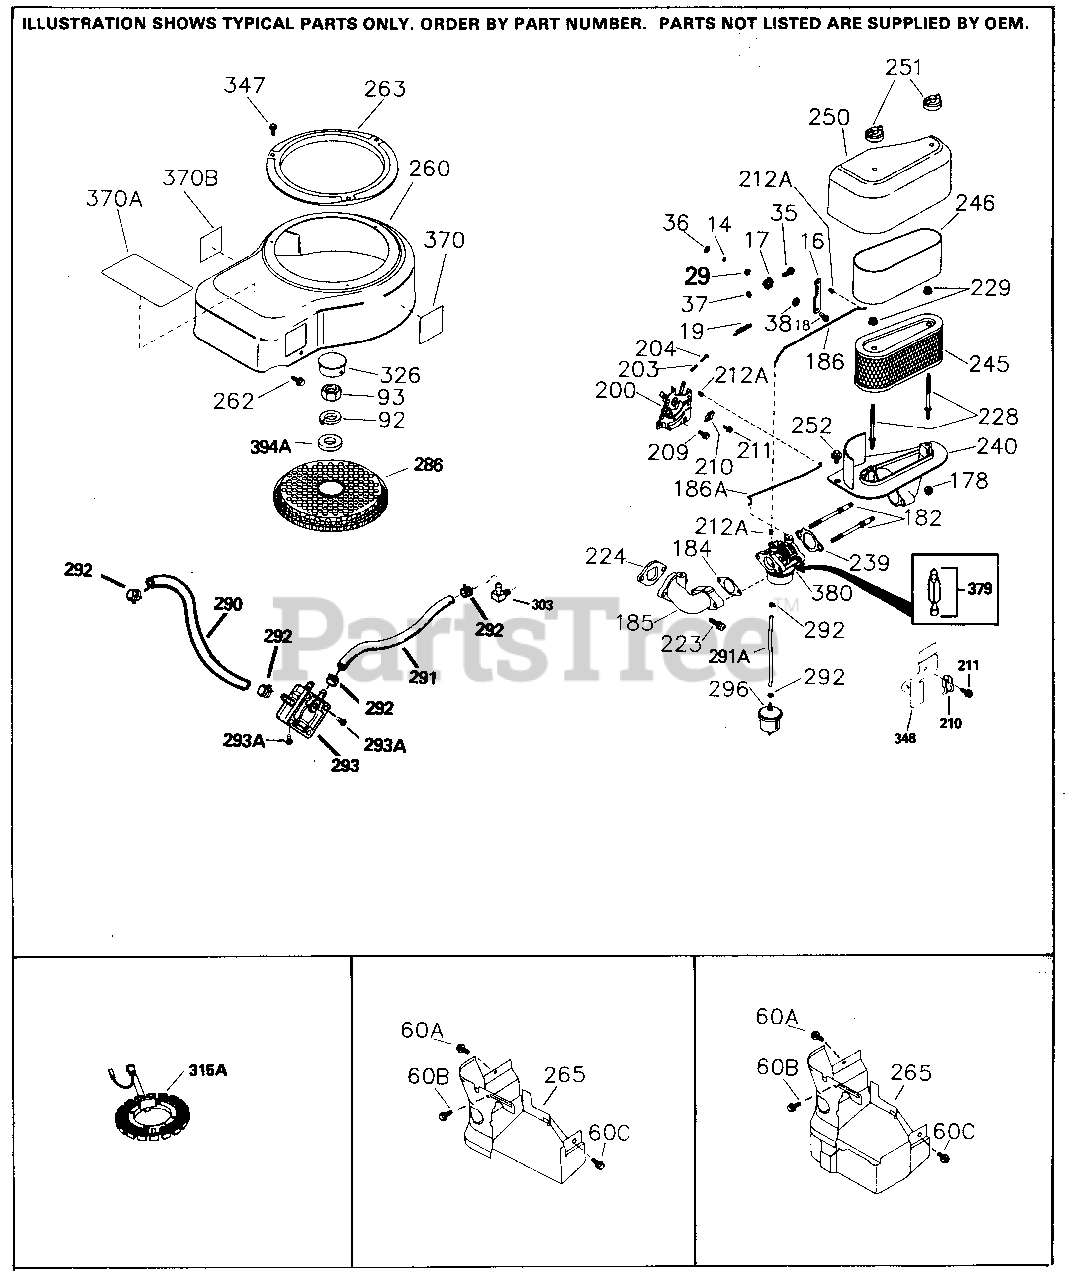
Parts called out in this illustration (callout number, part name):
14	Flat Washer
16	Governor Lever (Incl. 212A)
17	Governor Lever Clamp
18	Screw, 8-32 x 5/16"
19	Extension Spring
28	Lock Nut, 8-32
35	Screw, 10-32 x 3/4"
36	Lock Washer #8
37	Lock Nut, 10-32
38	Retaining Ring
50A	Camshaft Repair Kit
60A	Screw, 5/16-18 x 11/16"
60B	Screw, 10-24 x 1/2"
72A	Oil Drain Plug (3/8-18)
72B	Oil Drain Plug
90	Flywheel
92	Lock Washer
93	Flywheel Nut
130B	Screw, 1/4-20 x 1/2"
173	Breather Tube
178	Lock Nut, 1/4-20
182	Carburetor Mounting Stud
184	* Carburetor To Intake Pipe Gasket
185	Intake Pipe
186	Governor Link
186A	Choke Link
200	Control Bracket (Incl. 203,204,212A)
203	Compression Spring
204	Screw, 6-32 x 21/32"
210	Conduit Clip
211	Screw, 10-32 x 3/8"
212A	Bushing
223	Screw, Torx T-30, 5/16-18 x 1-9/32"
224	* Intake Pipe Gasket
228	Air Cleaner Stud
229	Nut & Lock Washer, 1/4-20
239	* Air Cleaner Gasket
240	Air Cleaner Body (Incl. 228 & 239)
243	Screw, 10-32 x 7/16"
245	Air Filter (Incl. 234) also available in Packaged Part #740055B
245A	Poly Pre-Filter (also available in Pa ckaged Part #740055B)
250	Air Cleaner Cover
251	Wing Nut, 1/4-20
252	Screw, 1/4-20 x 19/32"
260	Blower Housing
263	Trim Ring
264A	Screw, 1/4-20 x 5/8"
265	Cylinder Head Cover
266	Screw, 5/16-18 x 1-1/4"
286	Cup & Screen
290	Fuel Line
292	Fuel Line Clamp
296	Fuel Filter (Incl. 292) also availabl e as Packaged Part #740003B
322	Connector Body
323	Terminal
325A	Wire Clip
326	Screen Plug
347	Screw, 10-32 x 9/16"
365	Screw, 8-32 x 27/64"
370	Decal - Important Lubrication - SAE 3
380	Carburetor (Incl. 184 & 212A)
394A	Washer
